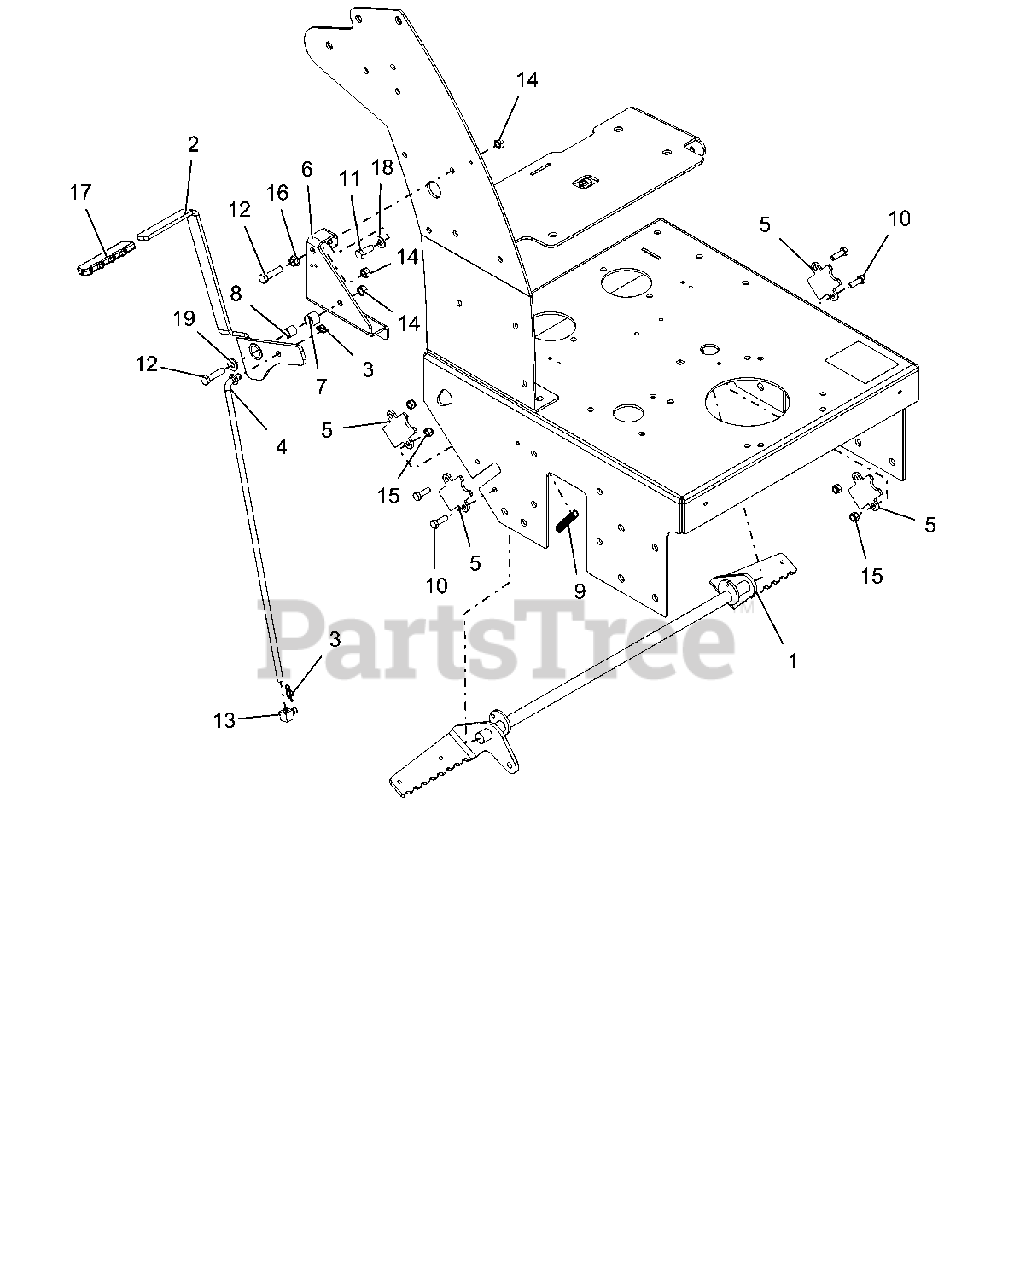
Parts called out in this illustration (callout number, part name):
1	WLDMT, BRAKE SYS FLOAT HYDRO-BLACK
2	HANDLE, PARK BRAKE
3	RING, RUE .375 x .054 x 1.254
4	ROD, DRIVE CONTROL FW
5	SHOE, BRAKE SYSTEM FLOAT WALK-RED
6	LOCATOR, BRAKE ARM WD-RED
7	PARK BRAKE HANDLE BUSHING
8	PARK, BRAKE LEVER SPACER
9	SPRG, EXTENSION
10	BLT-HEX .31-18X1.00 GR5 YWZC
11	BLT-HEX .38-16X1.00 GR5 YWZC
12	BLT-HEX .38-16X1.50 GR5 YWZC
13	SWIVEL, 3/8-24
14	NUT-LK-CTR .38-16 YWZC
15	NUT-LK-NYL .312-18 YWZC
16	@NUT-SPNLK-FLG .375-16 YWZC
17	GRIP
18	WSHR-FL-STL.406X.812X.065 YWZ
19	WSHR-FL-STL.38X.875X.083 YWZC
